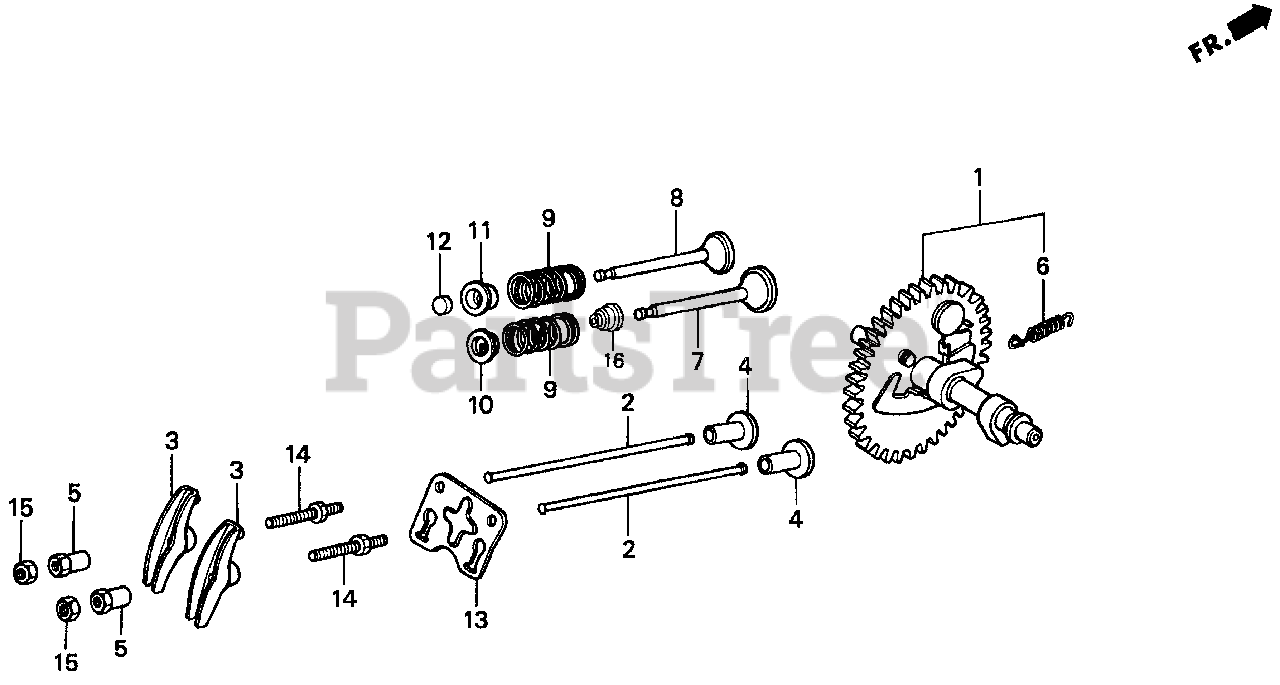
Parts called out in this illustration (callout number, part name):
1	CAMSHAFT ASSY.
2	ROD, PUSH
3	ARM, VALVE ROCKER
4	LIFTER, VALVE
5	PIVOT, ROCKER ARM
6	SPRING, WEIGHT RETURN
7	VALVE, IN.
8	VALVE, EX.
9	SPRING, VALVE
10	RETAINER, IN. VALVE SPRING
11	RETAINER, EX. VALVE SPRING
12	ROTATOR, VALVE
13	PLATE, PUSH ROD GUIDE
14	BOLT, PIVOT (8MM)
15	NUT, PIVOT ADJ.
16	SEAL, VALVE STEM
